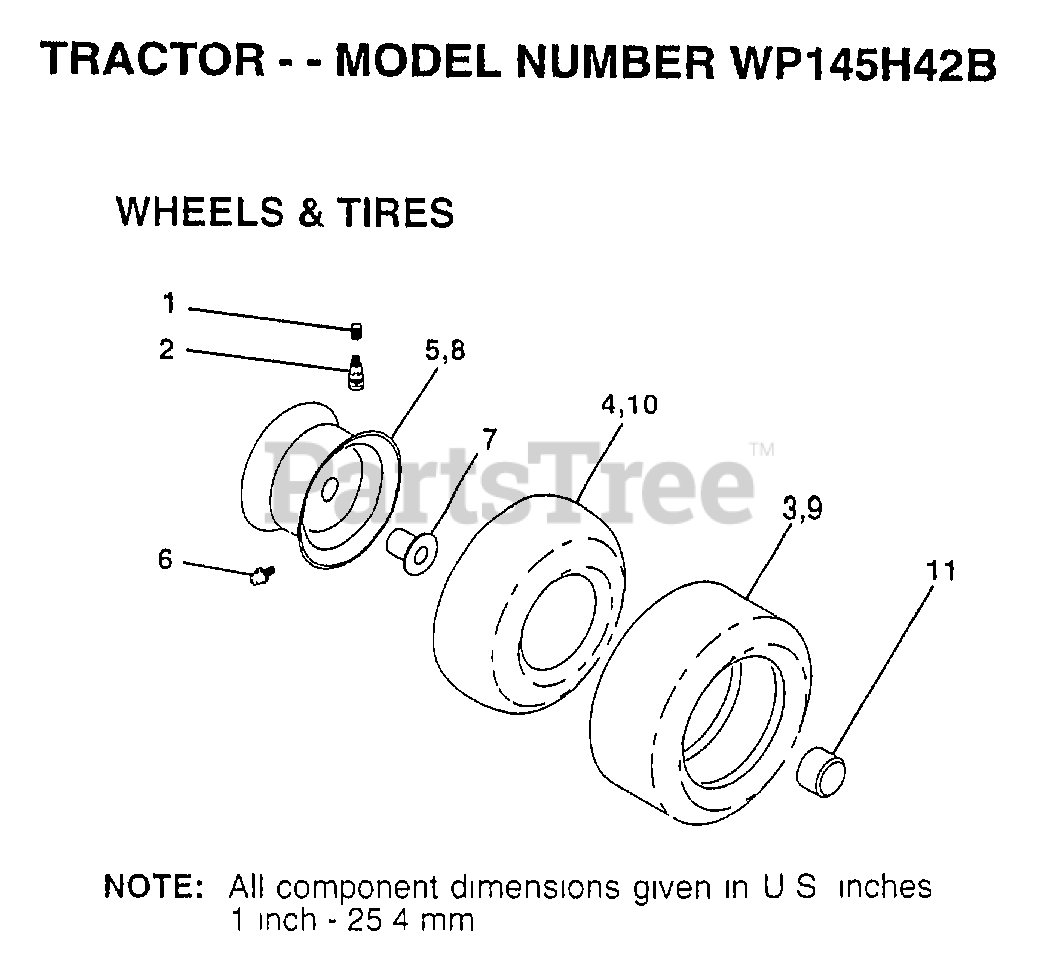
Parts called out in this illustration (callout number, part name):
1	VALVE CAP
2	VALVE STEM LT
4	TUBE.5.3/4.5/6
5	"RIM,FRT T"
6	FITTING LT
7	"FLANGE, BEARING"
8	"RIM 8"""
9	TIRE.20X8-8
10	TUBE.18X9.5-8
11	HUB CAP
